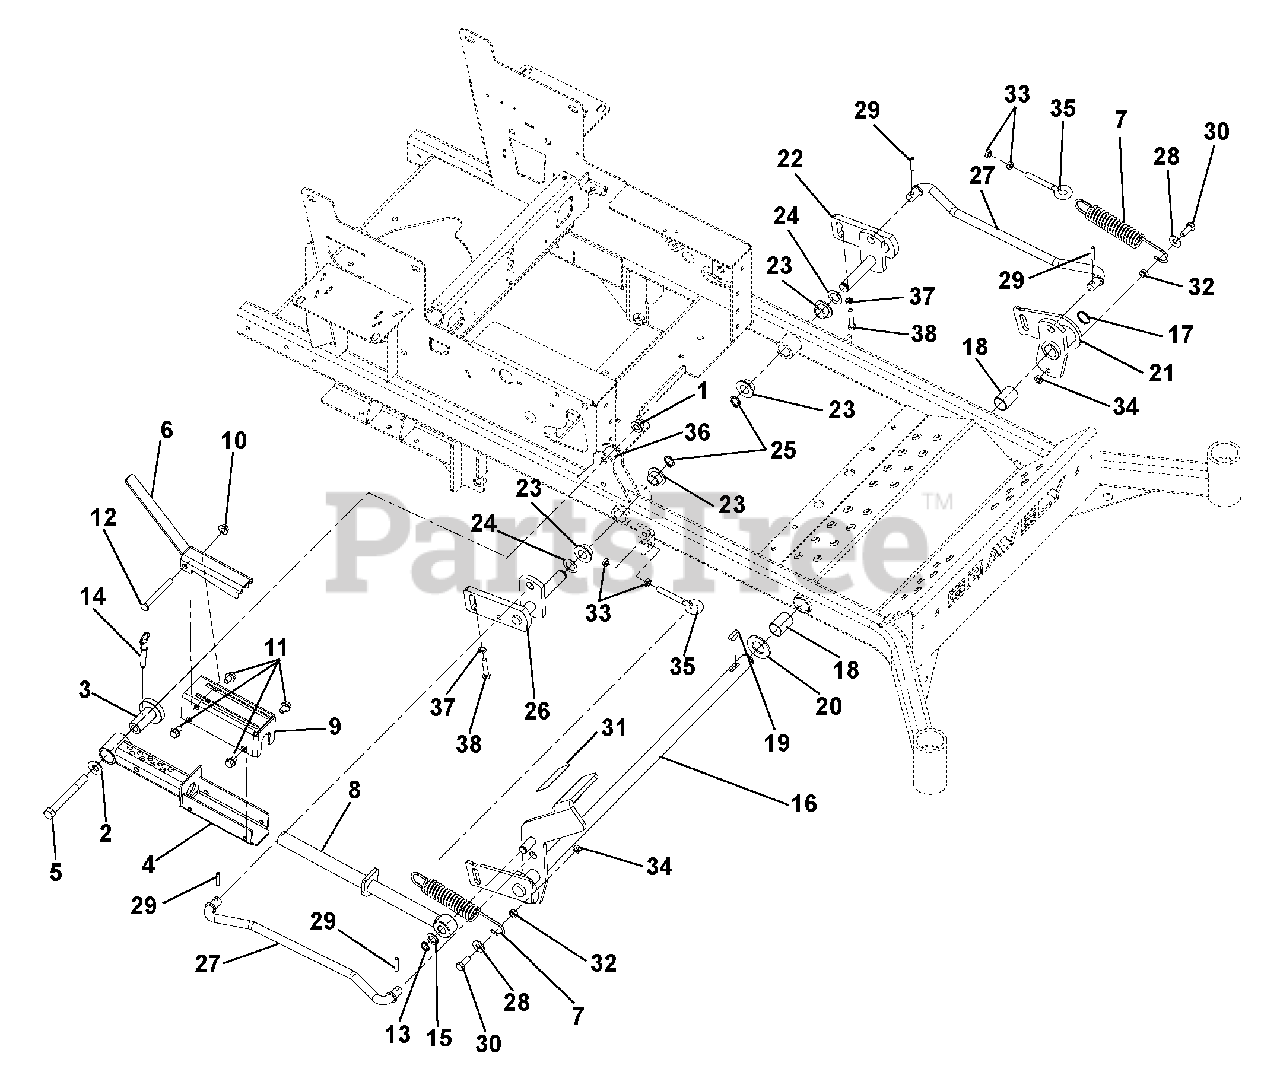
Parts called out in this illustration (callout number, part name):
1	NUT-LK-NYL-FLG .50-13 YWZC
2	WSHR-FL-STL .531X1.250X.10 YWZ
3	BEARING, PEDESTAL
4	WMT, MECHANICAL LIFT
5	BLT-HEX .50-13X4.50 GR5 YWZC
6	MECH DECK LIFT LOCK LEVER- BLK
7	SG-TENS .162X1.25X8.25 WLD 25
8	WMT, MECH. LIFT SHAFT (.62)
9	WMT, MECH LIFT COVER
10	NUT-LK-NYL-FLG .38-16 YWZC
11	SCR-TAP .38-16X.50 HWH TR YWZ
12	BLT-HEX .38-16X3.25 GR5 YWZC
13	RG-RTNG-EXT .625X.050
14	PIN, SPRING BALL .375OD X 1.50
15	WSHR-FL-STL .630X1.005X.062 YZ
16	WMT, 100I FOOT OPER DECK LIFT
17	RG-RTNG-EXT 1.00X.078
18	BSHG,1.00ID X 1.125OD X 1.50LG
19	KEY-WDRF .25X1.00 HRD #15
20	WSHR-FL-STL- 1.062X2.0X.134 YZ
21	WMT, LH FRONT MOWER LIFT
22	WMT-LH REAR LIFT ARM (DIESEL)
23	BSHG-FLG .762X1.0X.580X1.48 NY
24	WSHR-HDND-THRST .758X1.23X.031
25	RG-RTNG-EXT .689X.078
26	WMT-RH REAR LIFT ARM (DIESEL)
27	ROD, LIFT ASSIST 16.35"
28	WSHR-FL-STL.438X1.00X.083 YWZ
29	PIN-ROLL .250X1.25 STNLESS STL
30	BLT-HEX .38-16X1.00 GR5 YWZC
31	GRIP, PEDAL 1.50 X 3.00
32	BSHG-SLV .377X.624X.235
33	NUT-HEX-JAM .375-16 YWZC
34	NUT-LK-CTR-JAM .375-16 YWZC
35	BLT-EYE .375-16X2.50 YWZC
36	SPACER .516X1.000X.875
37	NUT- JAM .312-18 YWZC
38	BLT-HEX .312-18X1.50 FTH GR5YZ
